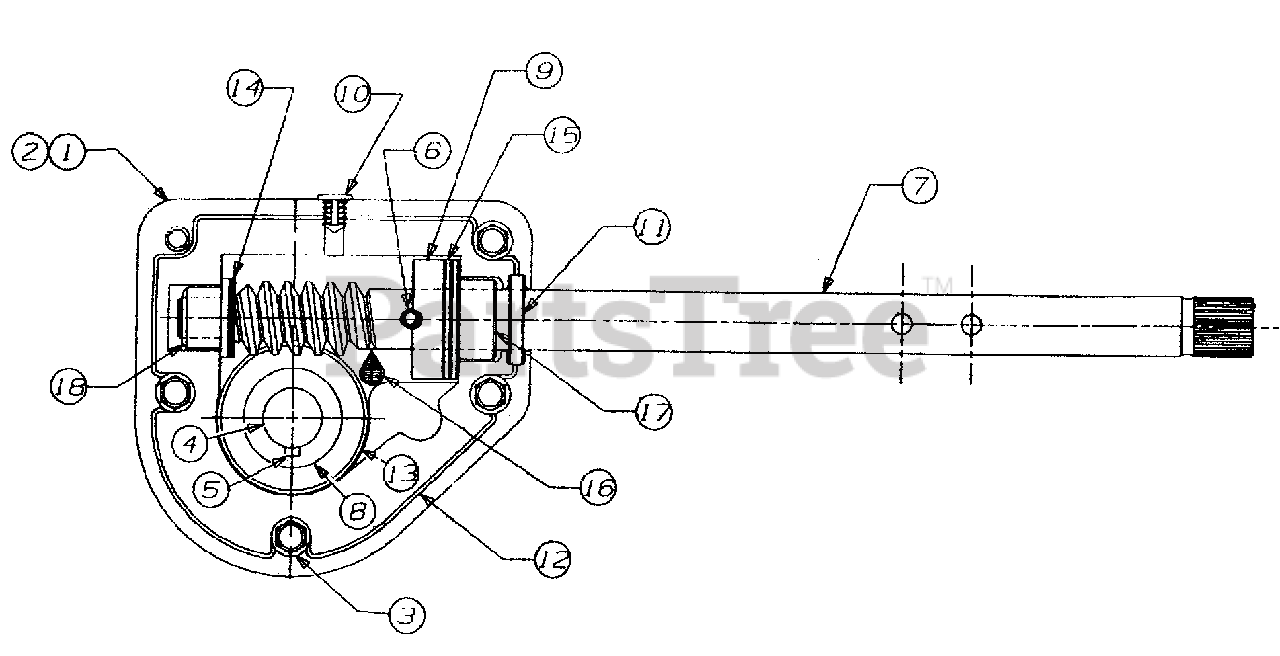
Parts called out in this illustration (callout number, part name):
1	Housing-R.H.
2	Housing-L.H.
4	Axle, Spiral 24" (724TE)
5	Key, Hi-Pro, 3/16 x 5/8
6	Pin, Spiral, .25 x 1.25
7	Worm, Shaft
8	Gear, Worm, 20T
9	Collar, Thrust
11	Seal, Oil, .75 x 1.131 x .188
12	Sealant, Loctite Ultra Grey 5699
13	Washer, Flat, .76 x 1.5 x .03
14	Washer,Flat, .5 x 1.0 x .02
15	Washer, Flat, .76 x 1.5 x .06
16	Grease
17	Bearing, Flange, .75 ID x 1.0 OD
18	Bearing, Flange, .75 x 1.0 x .925
